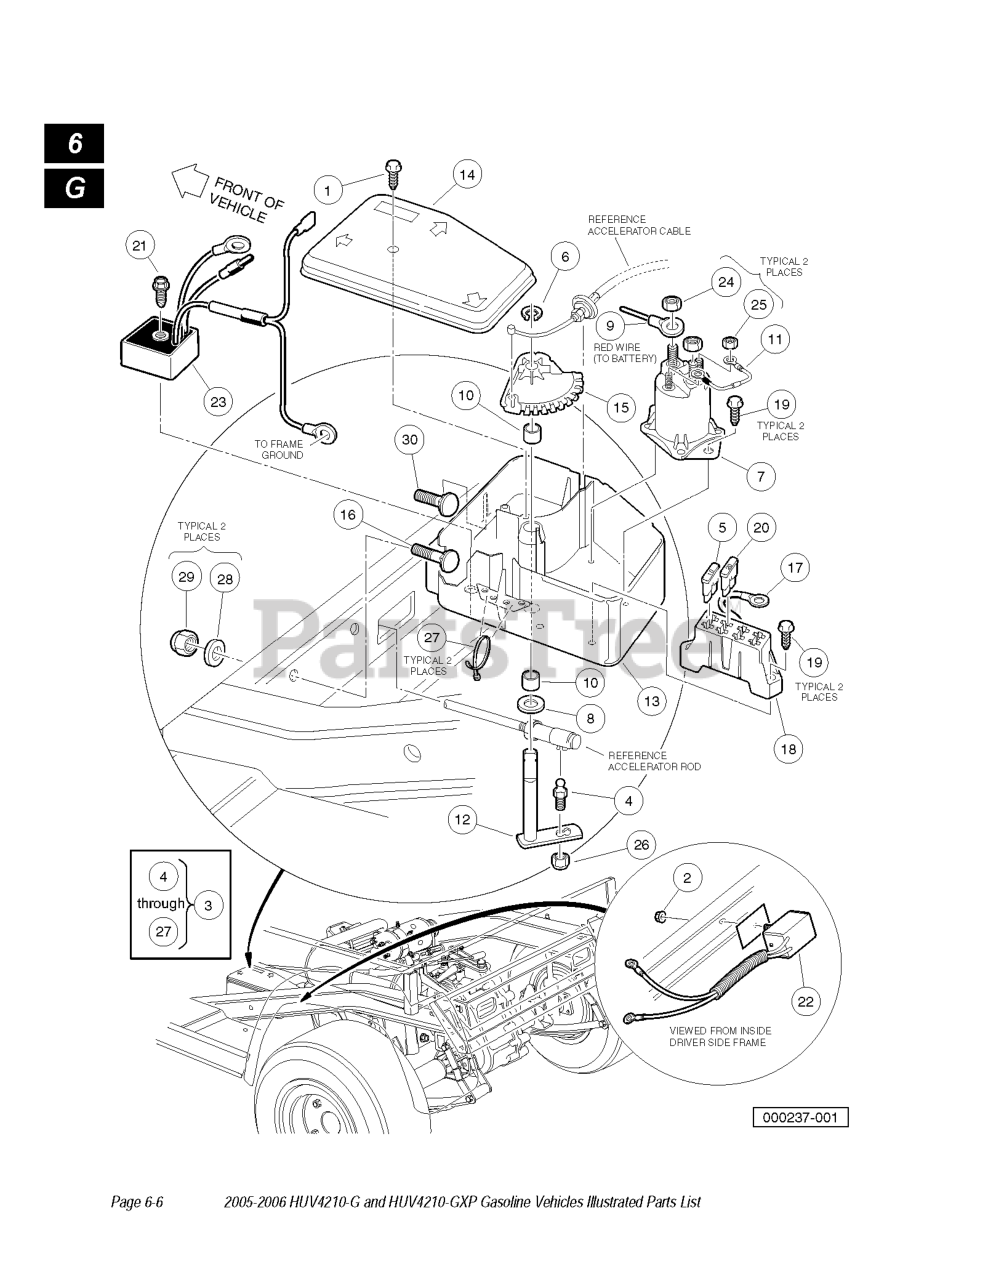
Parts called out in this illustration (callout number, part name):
1	SCREW, #12-16 X .625 HI-LO
2	LOCKNUT, 5/16-18 HEX FLANGE
5	10 AMP FUSE
7	SOLENOID, 12 VOLT
9	WIRE ASSY #6 RED
10	BUSHING, SECONDARY WGHT SPLIT
11	ASM, DIODE
12	BELL CRANK AND SHAFT ASSY
13	BOX, ELECTRICAL COMPONENT
14	COVER, OHV ELECTRIC BOX
15	CAM, ELECTRIC BOX
16	BOLT,5/16-18 X 2.0 RD HD SQ NK
17	WIRE ASSY, #10 RED
18	FUSE BLOCK
19	SCREW, #12-16 X .625 HI-LO
20	FUSE - 20 AMP
21	SCREW, 1/4-15 X .50 HI-LO HEX
22	DIODE ASSY
23	ASM, VOLTAGE REGULATOR
24	NUT, 5/16-18 HEX
25	NUT, #10-32 HEX
26	LOCKNUT, 1/4-28 NYLON INSERT
27	TIE WRAP, 8" NYLON
28	WASHER, 5/16 TYPE A FLAT
29	LOCKNUT, 5/16-18 NYLON INSERT
30	BOLT 5/16-18 X 1.5
